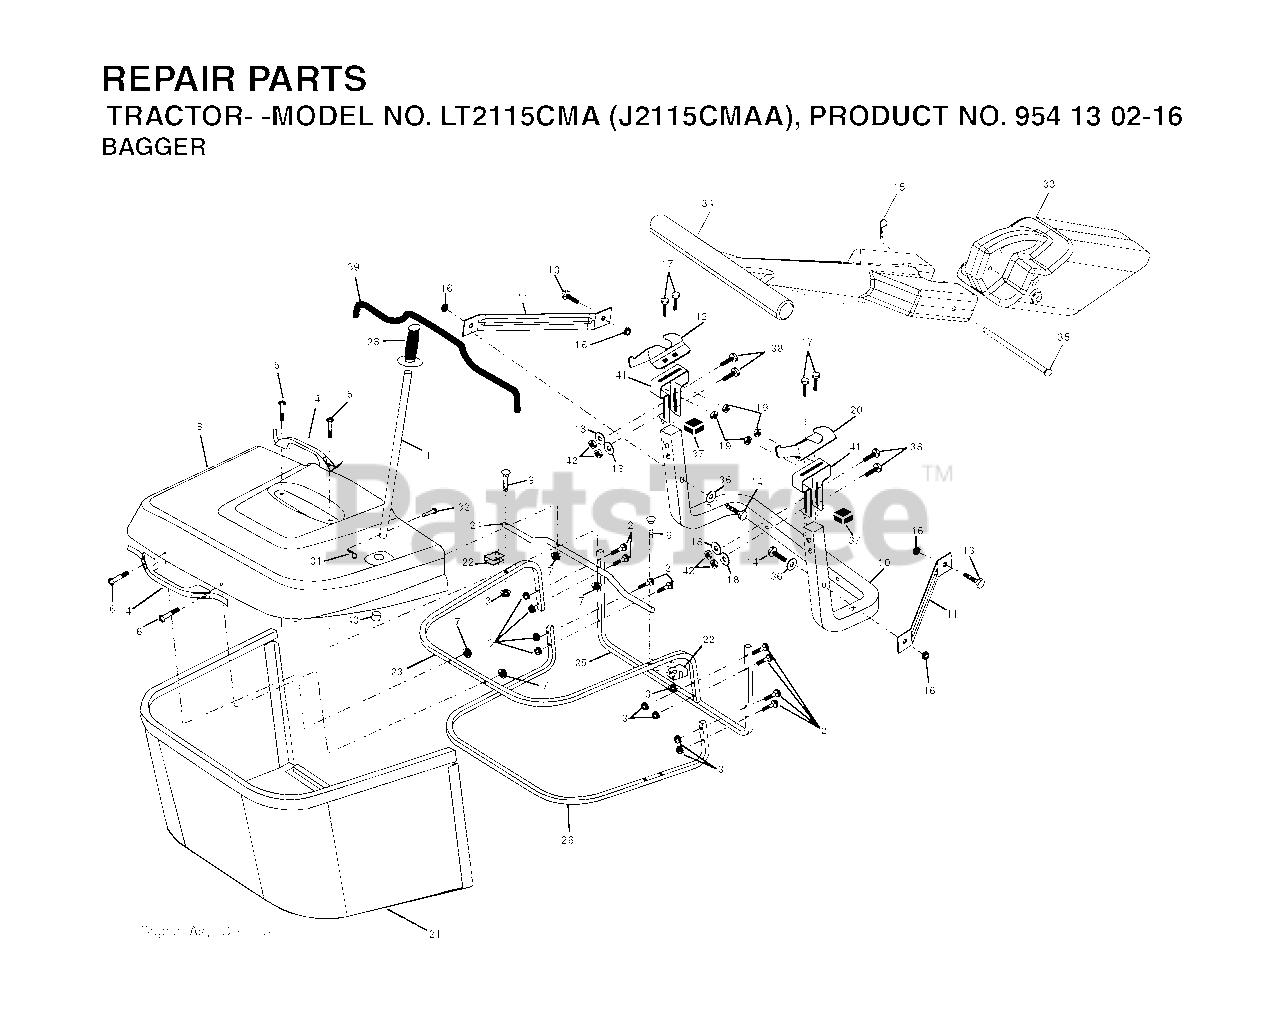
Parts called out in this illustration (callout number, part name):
1	TUBE HANDLE
3	NUT T
5	SCREW.PAN.HEAD
11	BRACKET
14	BOLT-HEX EAK
15	RETAINER-SPRNG RB
16	NUT LOCK FLG 3/8-16 UNC
17	BOLT
18	WASHER M
19	NUT LOCK HEX FLANGE 5/16-18
20	BRACKET
21	GRASS BAG
22	BRACKET
23	TUBE
24	TUBE
26	TUBE
28	GRIP.HANDLE.BLACK
31	RETAINER CLIP
32	RIVET,DRILLED
33	PLUG
35	PIN
36	WASHER
38	BOLT.5/16-18X2.5
41	BRKT, BAGGER
42	NUT.71038.31-18.HEX.NYLOCK
43	PLUG, TUBING END
